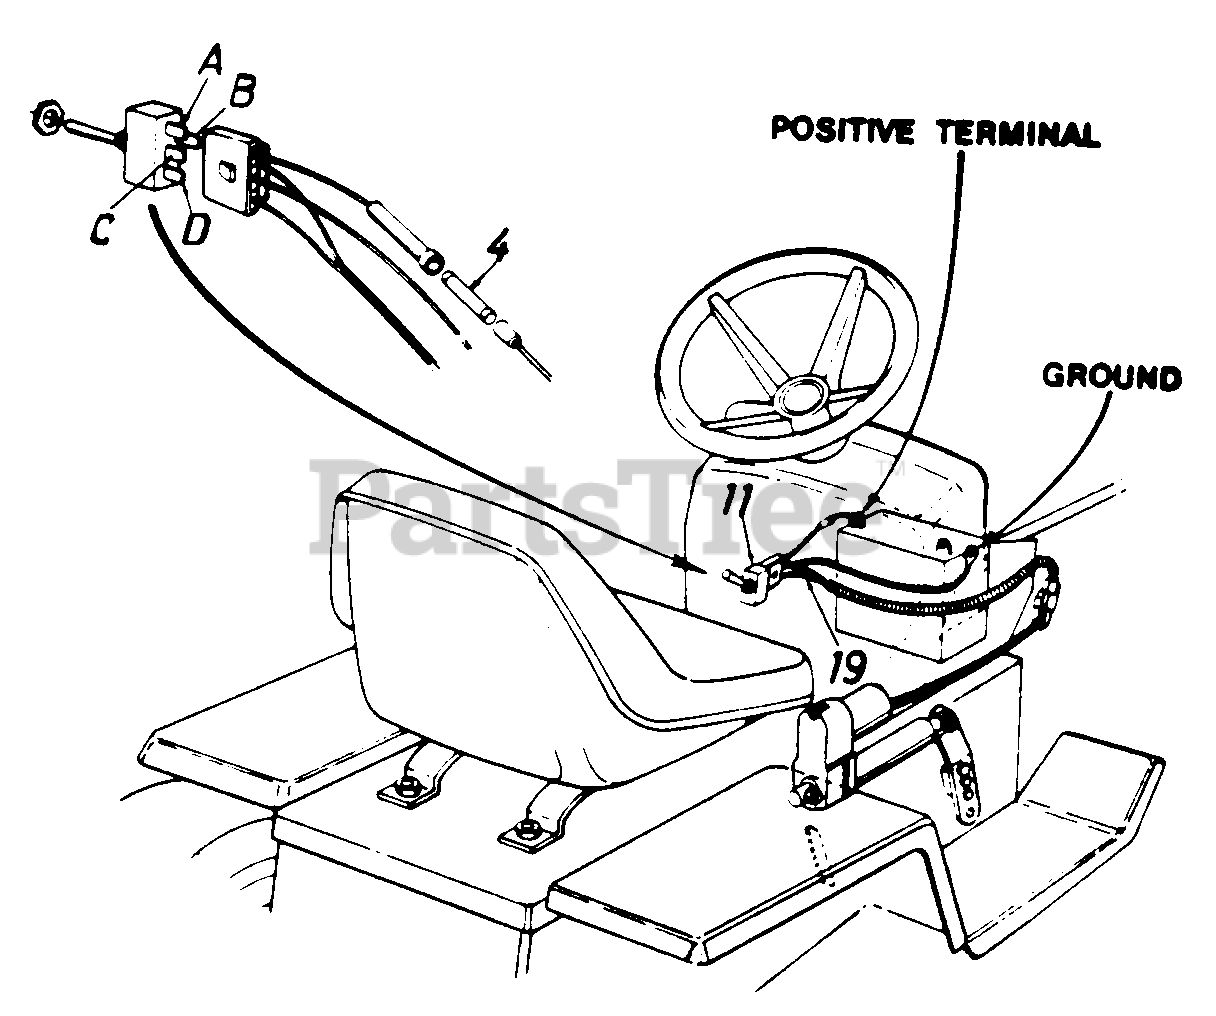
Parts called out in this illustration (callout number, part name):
4	Fuse 30 AMP
11	Toggle Switch
19	Wire Harness
A	Blue Wire-Connects to Positive Terminal on Battery
B	Yellow Wire-Connects to Actuator
C	Black Wire-Ground Wire-to Frame
D	Red Wire-Connects to Actuator
